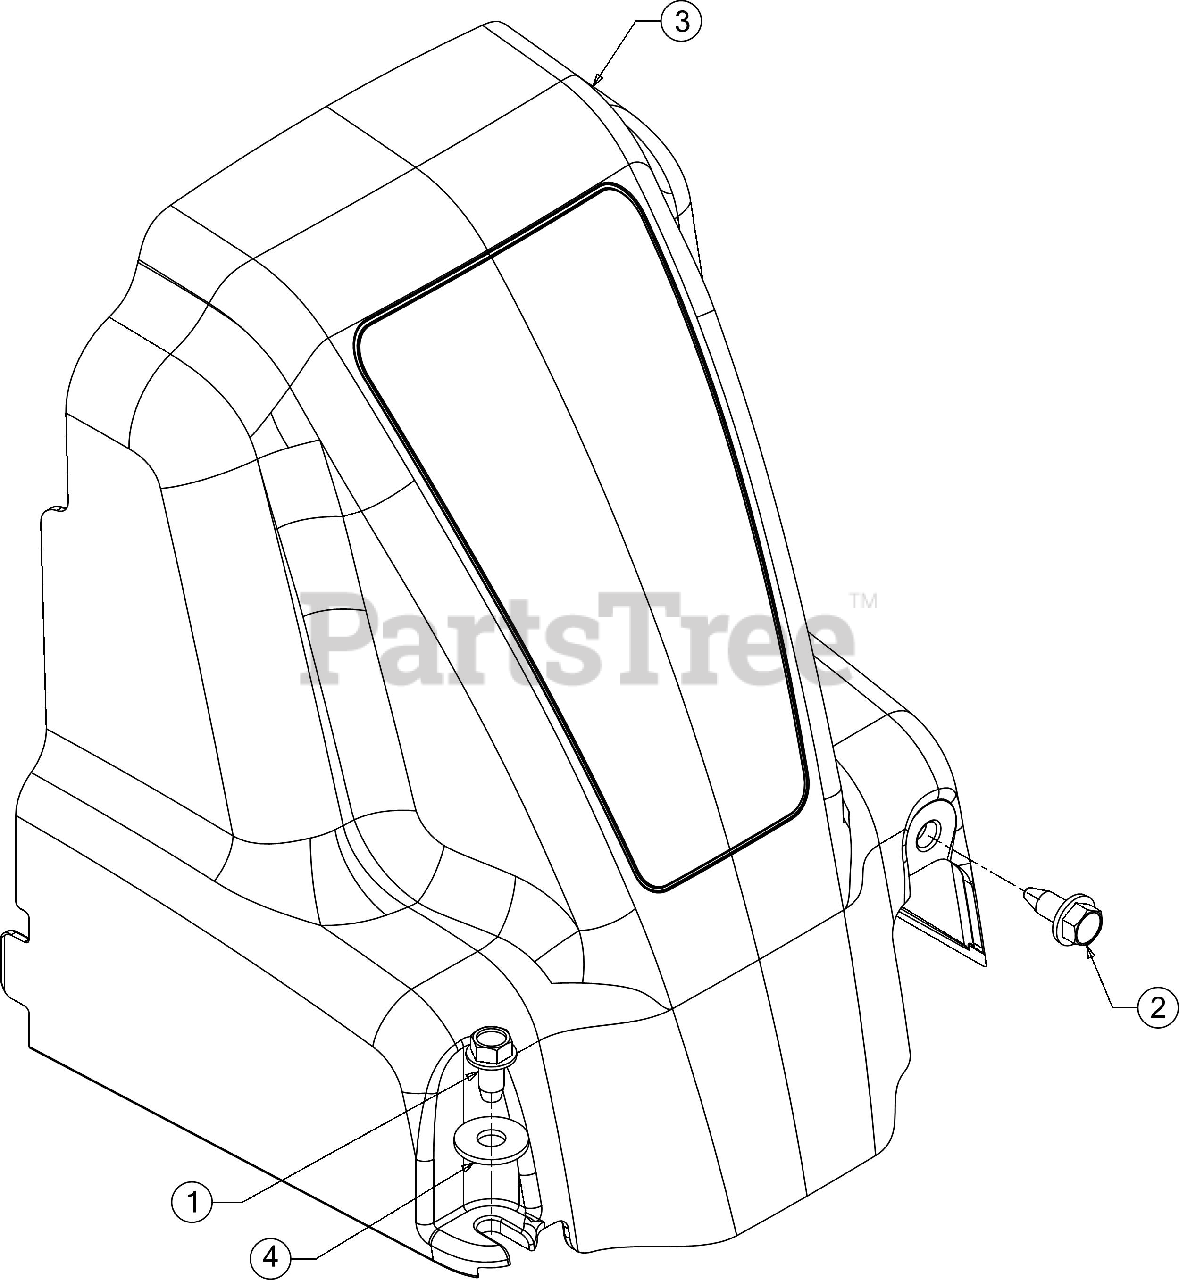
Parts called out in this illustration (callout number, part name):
1	SCREW 1/4-20 X.500
2	SCREW 1/4-14 x .625
3	BELT COVER
4	FLAT WASHER .28 ID x .74 OD x .063
